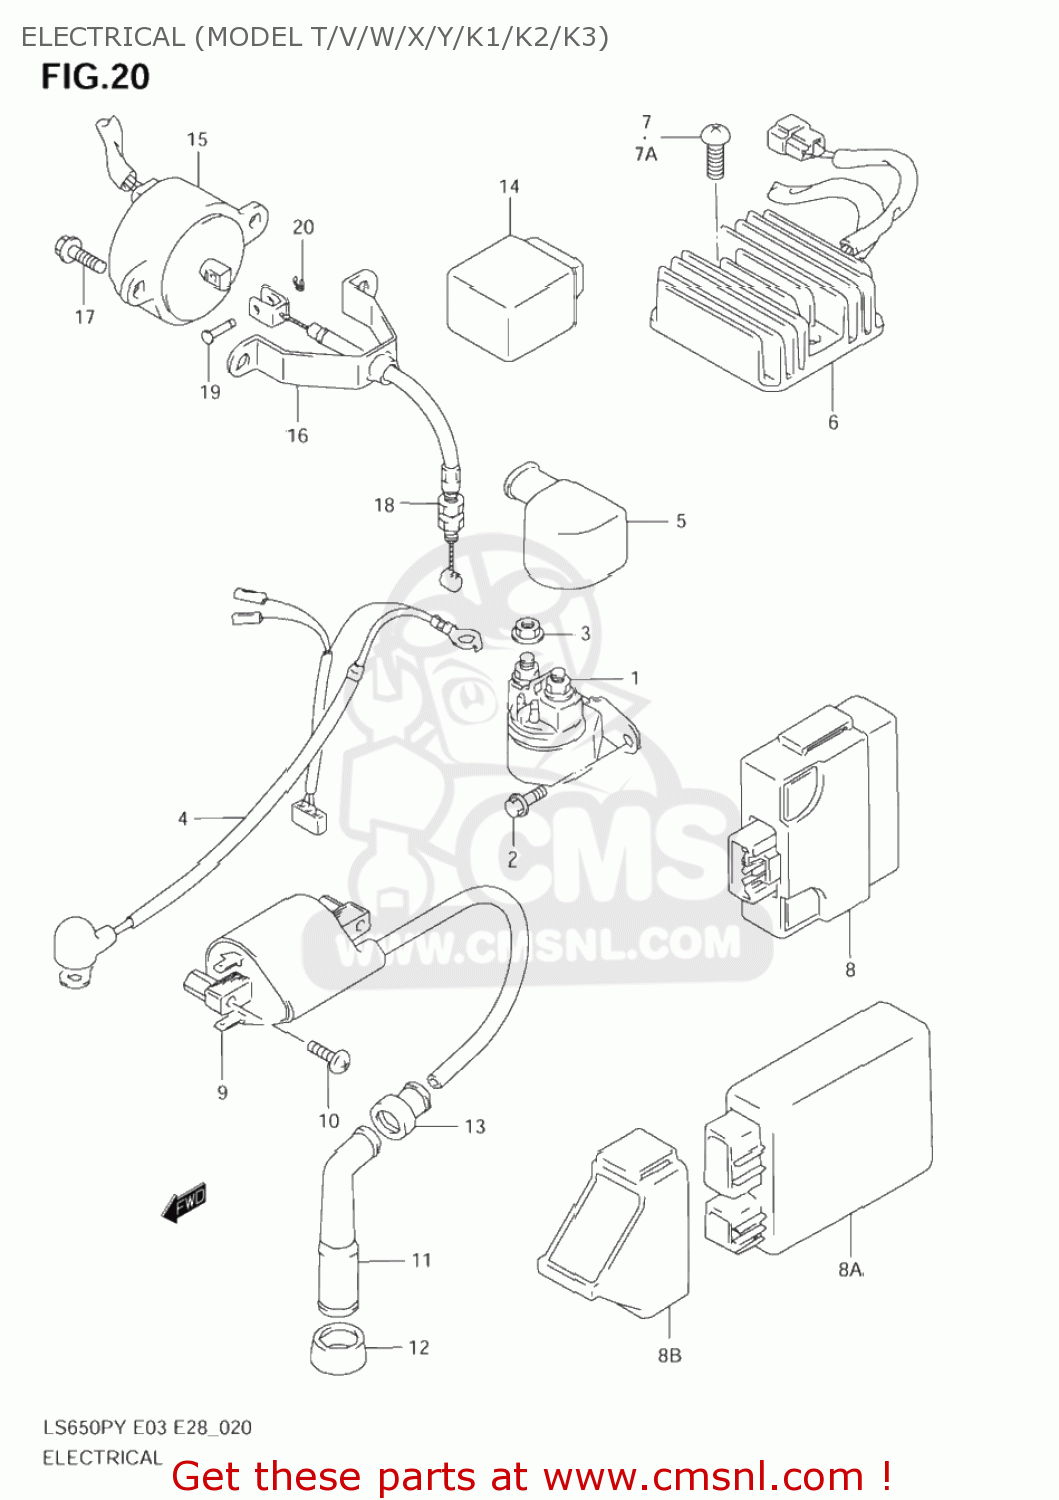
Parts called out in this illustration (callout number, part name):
1	RELAY ASSY,STARTING MOTOR
2	BOLT
3	NUT
4	WIRE,STARTER MOTOR
5	CAP,STARTER RELAY TERMINAL
6	RECTIFIER ASSEMBLY
7	SCREW
7A	SCREW
8	IGNITER ASSEMBLY
8A	IGNITER ASSEMBLY
8B	CUSHION,IGNITOR
9	COIL ASSY,IGNITION
10	SCREW 5X12
11	CAP ASSY,SPARK PLUG
12	SEAL,SPARK PLUG CAP
13	SEAL,HIGH TENSION CORD
14	CONTROL UNIT,DECOMP
15	SOLENOID ASSY,DECOMP
16	BRACKET,DECOMP SOLENOID
17	BOLT
18	CABLE ASSEMBLY,DECOMPRESSION
19	PIN(4X12.5)
20	E RING
